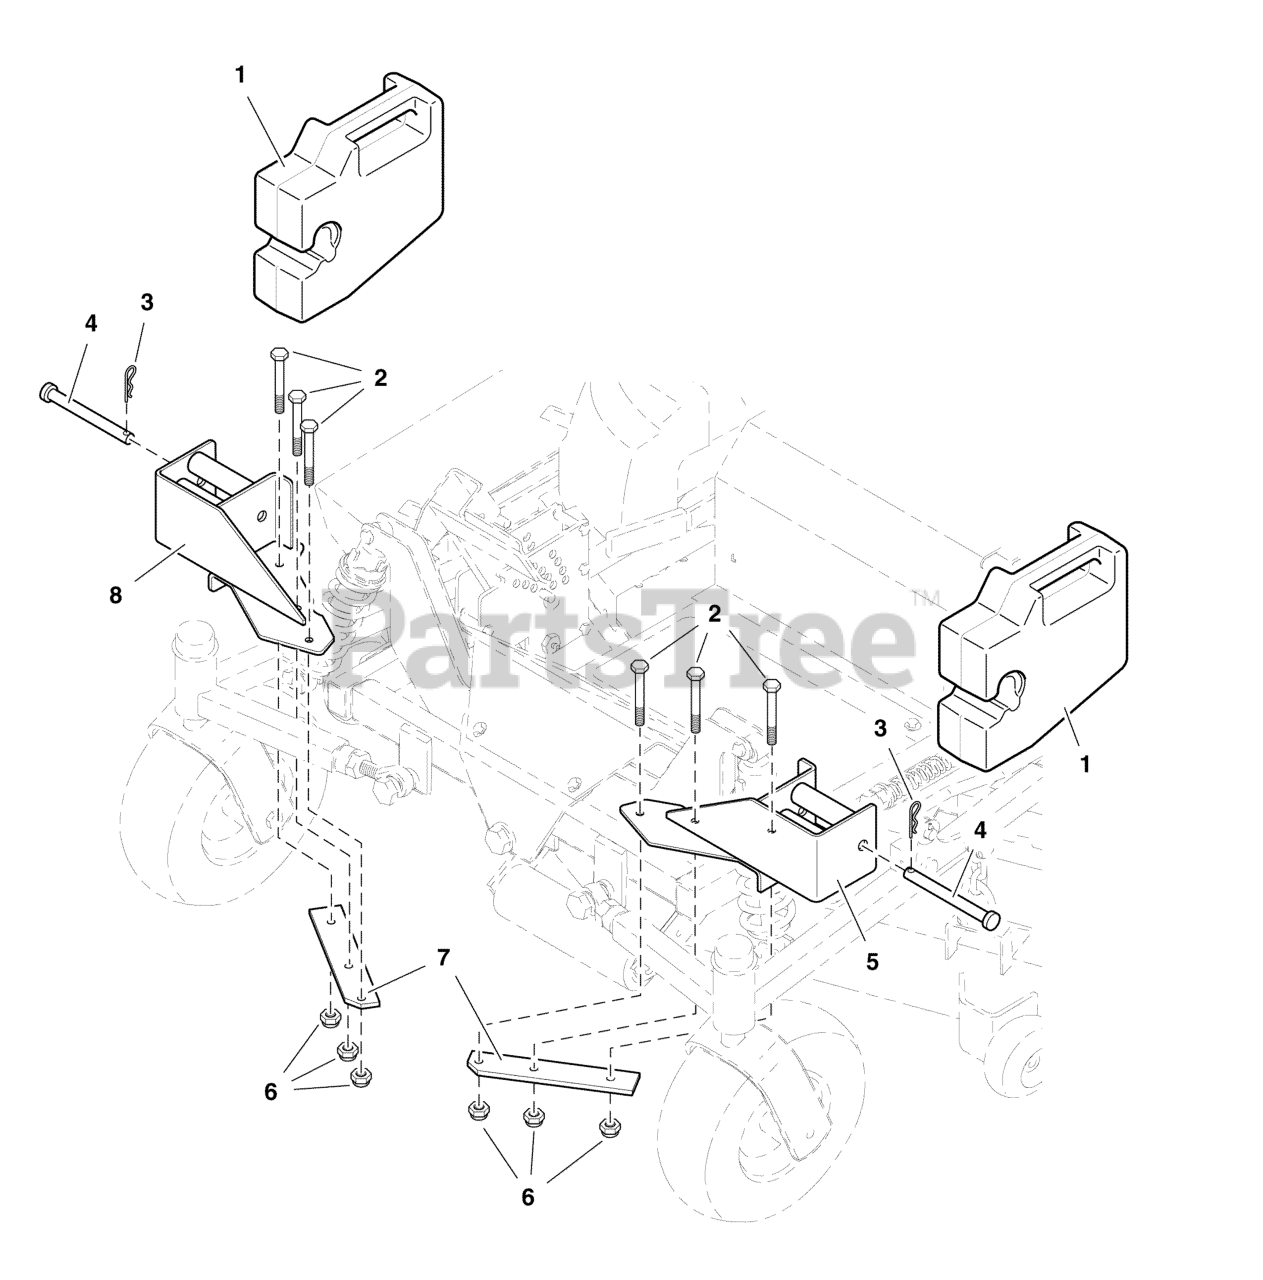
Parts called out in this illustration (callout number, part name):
1	WEIGHT-QUICK ATTACH 50LB SUITCASE PAINTED
2	BOLT, 5/16-18 X 2-1/2" GD5 YZ
3	PIN, HAIR, .0915 X 1-7/8
4	PIN,CLEVIS, 1/2" X 4 1/2",PLTD
5	WEIGHT MOUNT BRACKET W'MENT-LH
6	NUT, 5/16-18 HEX NYLON LOCK
7	CLAMP, BAR
8	WEIGHT MOUNT BRACKET W'MENT-RH
